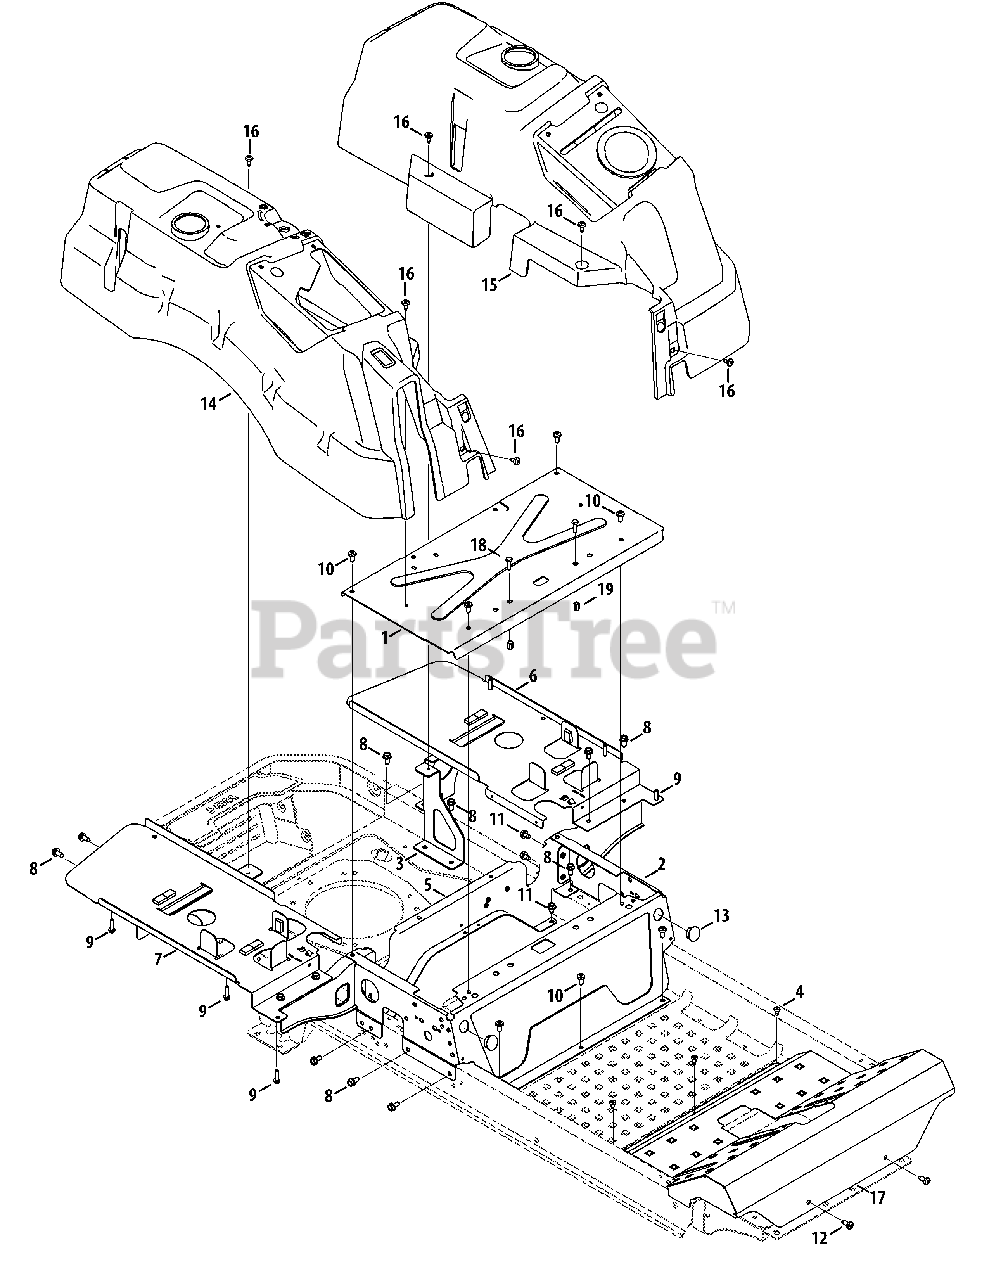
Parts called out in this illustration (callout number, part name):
1	Seatbox Plate
2	Seat Frame
3	Rear Support Bracket, LH
3	Rear Support Bracket, RH
4	Screw, 1/4-20 x .50
5	Rear Seatbox Brace
6	Tank Support Plate, LH
7	Tank Support Plate, RH
8	Hex Washer Screw, 5/16-18 x .750
9	Hex Washer Screw, 5/16-14 x 1.00
10	Self Tapping Screw, 5/16-18 x .750
11	Hex Washer Screw, 5/16-18 x .50
12	Screw, 5/16-18 x .75
13	Plastic Plug
14	RH Console
15	LH Console
16	Shoulder Screw, 1/4-20
17	Floor Board, Fab
18	Hex Cap Screw, 5/16-18 x 1.00
19	Nut, 5/16-18
